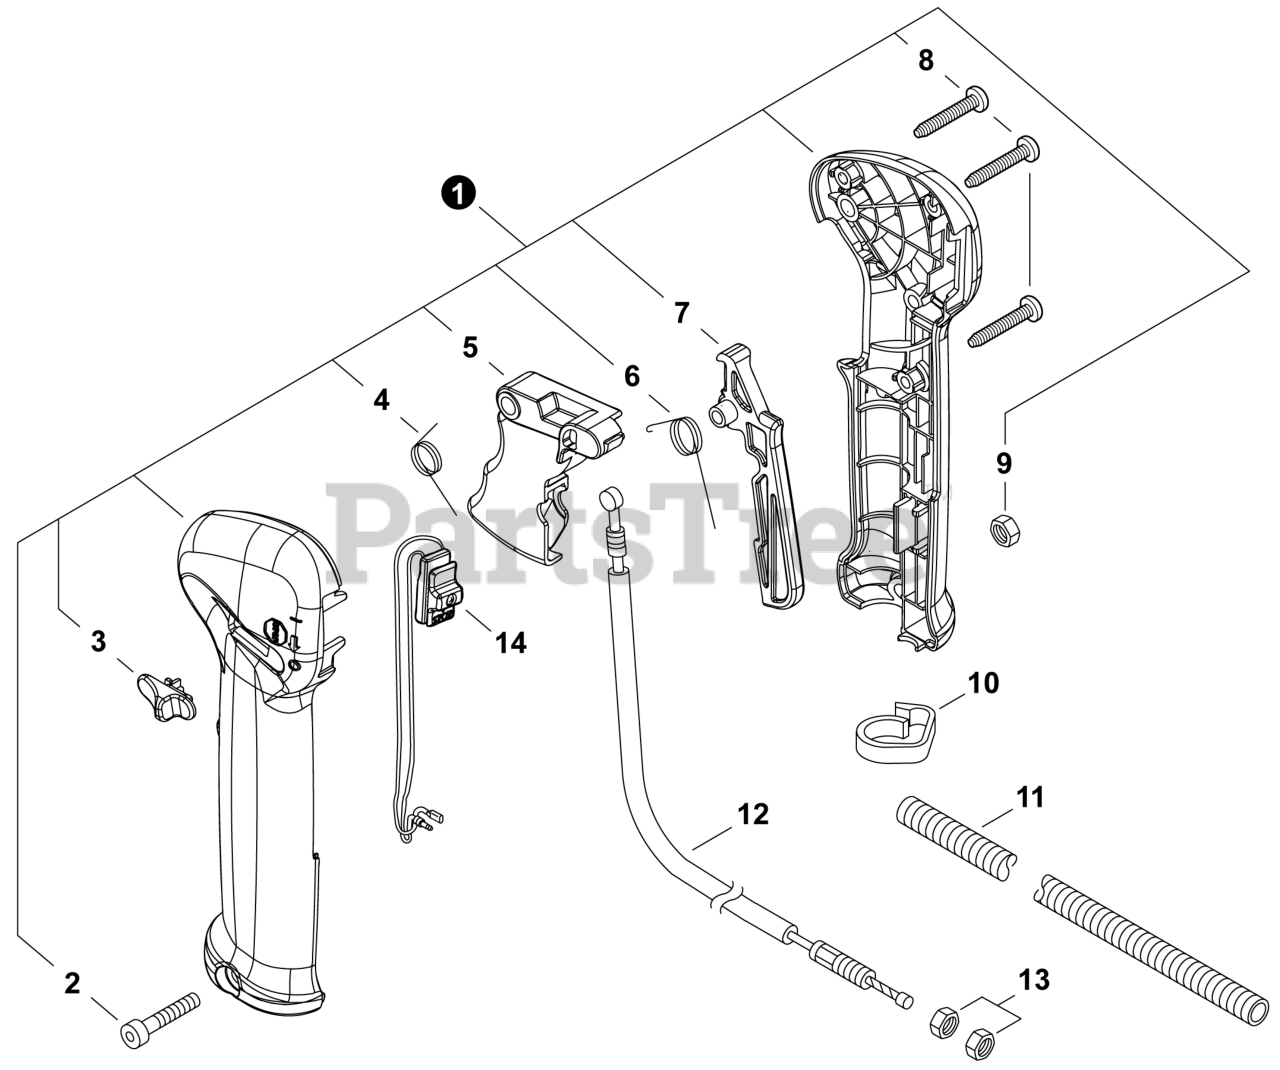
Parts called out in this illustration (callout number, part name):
1	CONTROL HANDLE ASSY
2	BOLT - 5x30
3	LATCH, THROTTLE
4	SPRING, TORSION
5	TRIGGER, THROTTLE
6	SPRING, TORSION
7	LOCKOUT, THROTTLE
8	SCREW 4x16
10	CLIP, CABLE
11	TUBE, FLEXIBLE 7x740
12	CABLE, THROTTLE
14	SWITCH, ON-OFF
